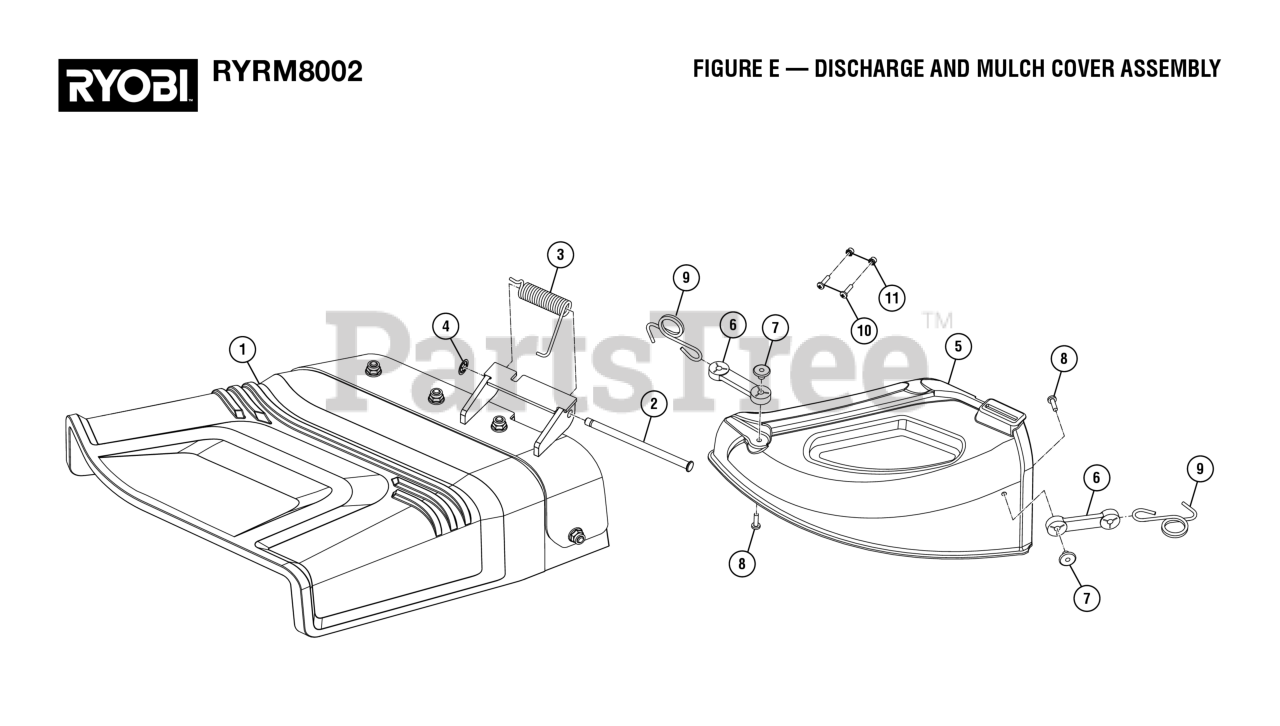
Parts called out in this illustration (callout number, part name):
1	Side Discharge Chute Assembly
2	Discharge Chute Hinge
3	Discharge Chute Spring
4	Retainer Clip
5	Mulch Plug, ZTR
6	RUBBER STRAP, MULCHING COVER
7	ANCHOR, BUNGIE, RIDING MOWER
8	SCREW,PPHMS, M5 X 0.8 X 16 - STEEL,
9	SPRING, LATCH
10	Screw (M4 x 15 mm)
11	Nut (M4 x 0.7, Lock)
